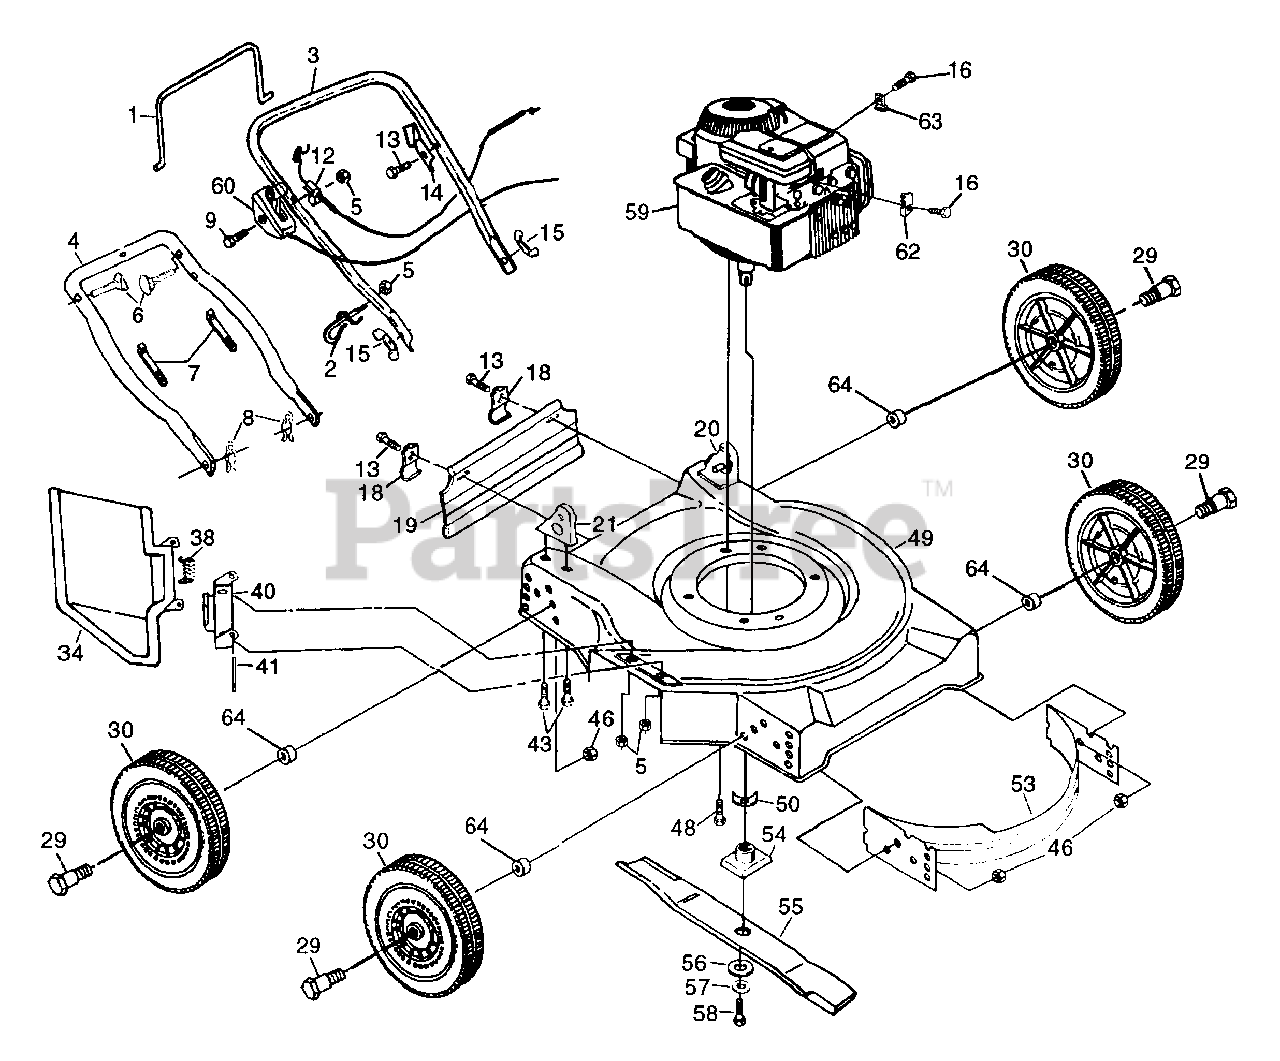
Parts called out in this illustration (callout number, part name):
1	Control Bar
2	Rope Guide
3	Upper Handle
4	Lower Handle
5	Locknut 1/4-20
6	Handle Bolt 5/16-18
7	Wire Tie
8	Hairpin Cotter
9	Machine Screw 1/4-20 x 2
12	Engine Zone Control Cable
13	Hex Washer Head Screw #10-24 x 1/2
14	Up-Stop Bracket
16	Screw #10 x 5/8
18	Skirt Bracket
19	Rear Skirt
20	Handle Bracket Assembly (Left)
21	Handle Bracket Assembly (Right)
29	Shoulder Bolt
30	Wheel & Tire Assembly
34	Discharge Guard
38	Spring
40	Housing Bracket
43	Thread Cutting Screw 5/16-18 x 3/4
46	Locknut 3/8-16
48	Hex Head Thread Rolling Screw 3/8-16 x 1-1/8
49	Housing Assembly
53	Baffle
54	Blade Adapter
56	Hardened Washer
57	Helical Lockwasher 3/8
58	Hex Head Screw 3/8-24 x 1-3/8 Gr. 8
59	Engine
60	Throttle Control Std.
62	Cable Clamp, B & S
63	Engine Clip
